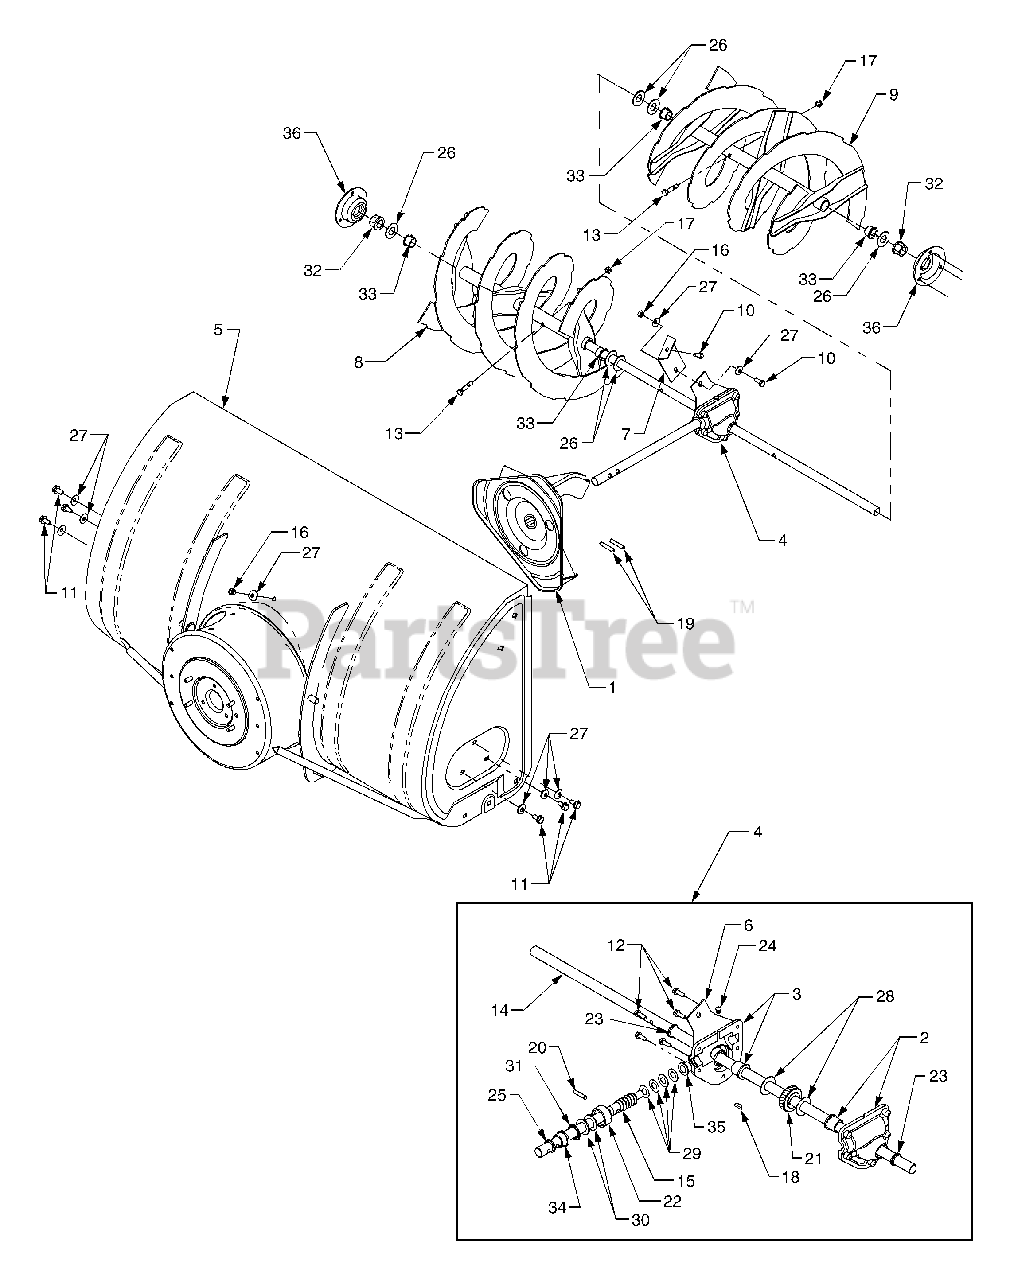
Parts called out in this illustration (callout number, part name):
1	Impeller Assembly
2	Housing Assembly, Auger RH
3	Housing Assembly, Auger LH
4	Auger Gear Box Ass'y., Complete
5	Housing, Auger
6	Plate, Housing Brace
7	Bracket, Housing Brace
8	Auger, Serrated, LH
9	Auger, Serrated, RH
10	Screw, Hex Cap 5/16-24 x .75 GR5
11	Screw, Hex Wash. Hd. Tapp 5/16-18 x .625
12	Screw, Hex Wash. Hd. Tapp 1/4-20 x .75
13	Shear Bolt, 5/16-18
14	Shaft, Auger
15	Shaft, Worm Gear
16	Nut, Hex, 5/16-24 GR2
17	Nut, Hex, Insert Lock, 5/16-18
18	Key, Hi-Pro, 3/16 x 5/8
19	Pin, Spiral Spring, 1/4 x 1-1/2
20	Pin, Spiral Spring, 1/4 x 1.25
21	Gear, Worm, 20T
22	Collar, Thrust
23	Seal, Oil
25	Seal, Oil
26	Washer, Flat, .76 x 1.49 x .06
27	Washer, Bell, .340 x .872 x .06
28	Washer, Flat, .76 x 1.5 x .030
29	Washer, Flat, .508 x 1.0 x .020
30	Washer, Thrust, .75 x 1.25 x .062
31	Bearing, Thrust,
32	Bearing, Hex Flange
33	Bushing, Flange
34	Bearing, Flange
35	Bearing, Flange
